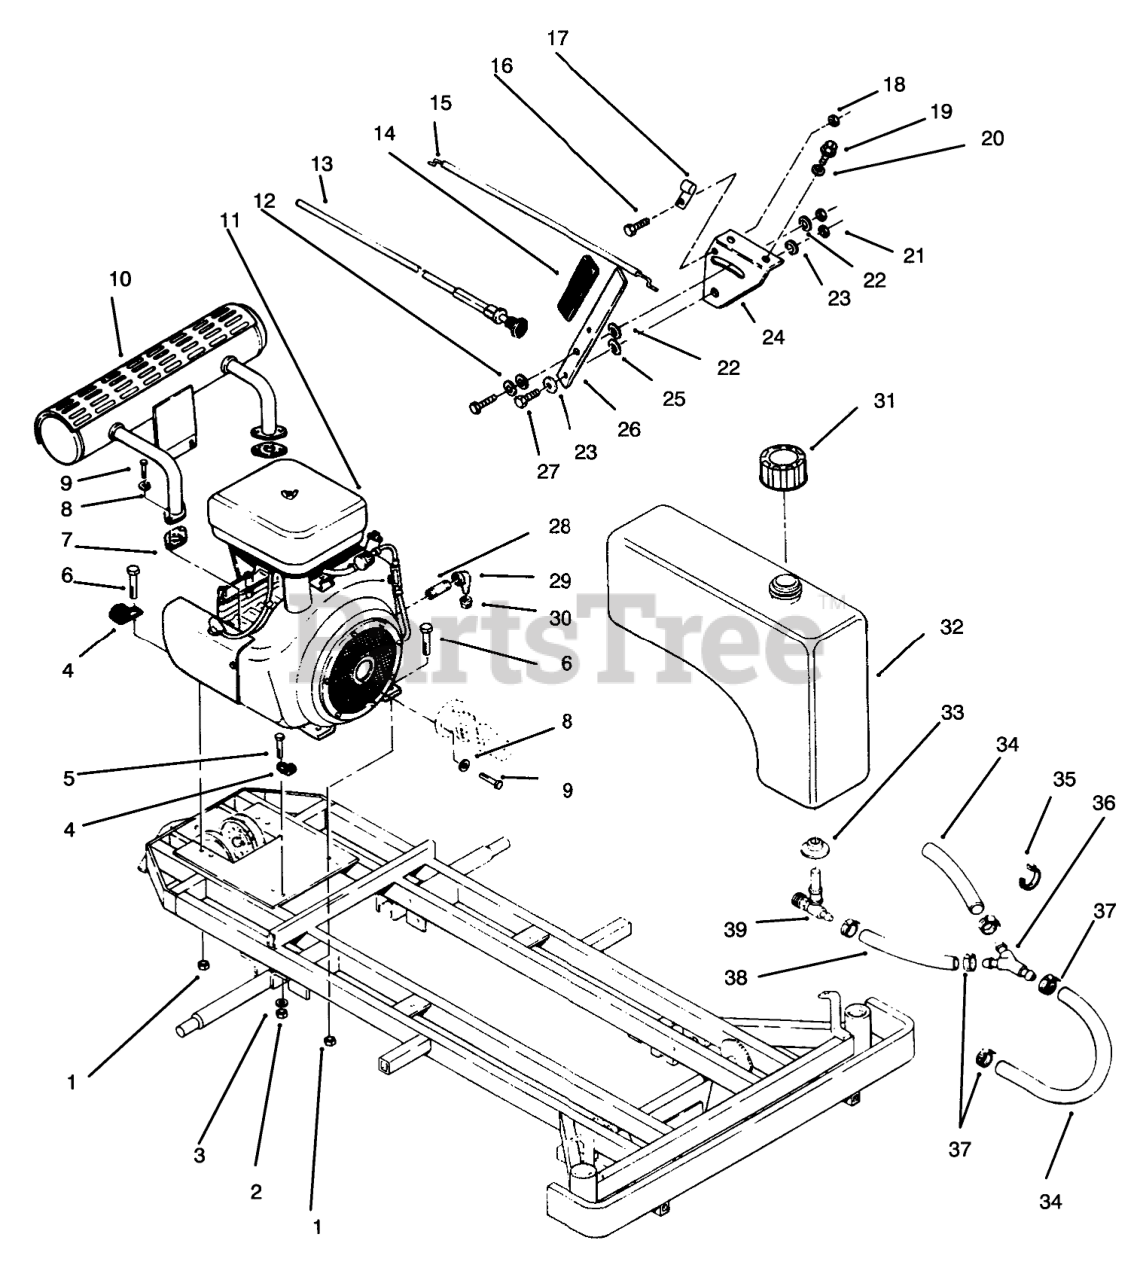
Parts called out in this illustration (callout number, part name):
1	NUT-LOCK, NI
2	NUT-LOCK, NI
3	WASHER-PLAIN
4	CLIP
5	SCREW-HH
6	SCREW-HHF
7	GASKET-EXHAUST
8	WASHER-LOCK
9	SCREW-HSH
10	MUFFLER
11	Engine-24 HP Toro Power Plus P224 G I/10966 Spec. E Engine
12	WASHER-SPRING DISC
13	CABLE-CHOKE
14	GRIP BRAKE20258-K
15	CABLE-CHOKE CONTROL
17	CLIP BOWDEN WIRE
18	NUT-LOCK, NI
19	SCREW-HH
20	WASHER-LOCK
22	FRICTION WASHER
23	WASHER-FLAT
24	CABLE/BRKT ASM
25	SPACER CLUTCH ARM
26	Handle
27	SCREW-HH
28	NIPPLE-PIPE
29	ELBOW-STREET, 90 DEG
30	CAP-PIPE
31	GAS CAP ASM
32	Tank-Fuel (Incl.Items #33 & 39)
33	BUSHING
34	HOSE-GAS
35	TIE-CABLE
36	FITTING-FUEL 45-Y
37	CLAMP-HOSE
38	HOSE-FUEL
39	VALVE-FUEL
